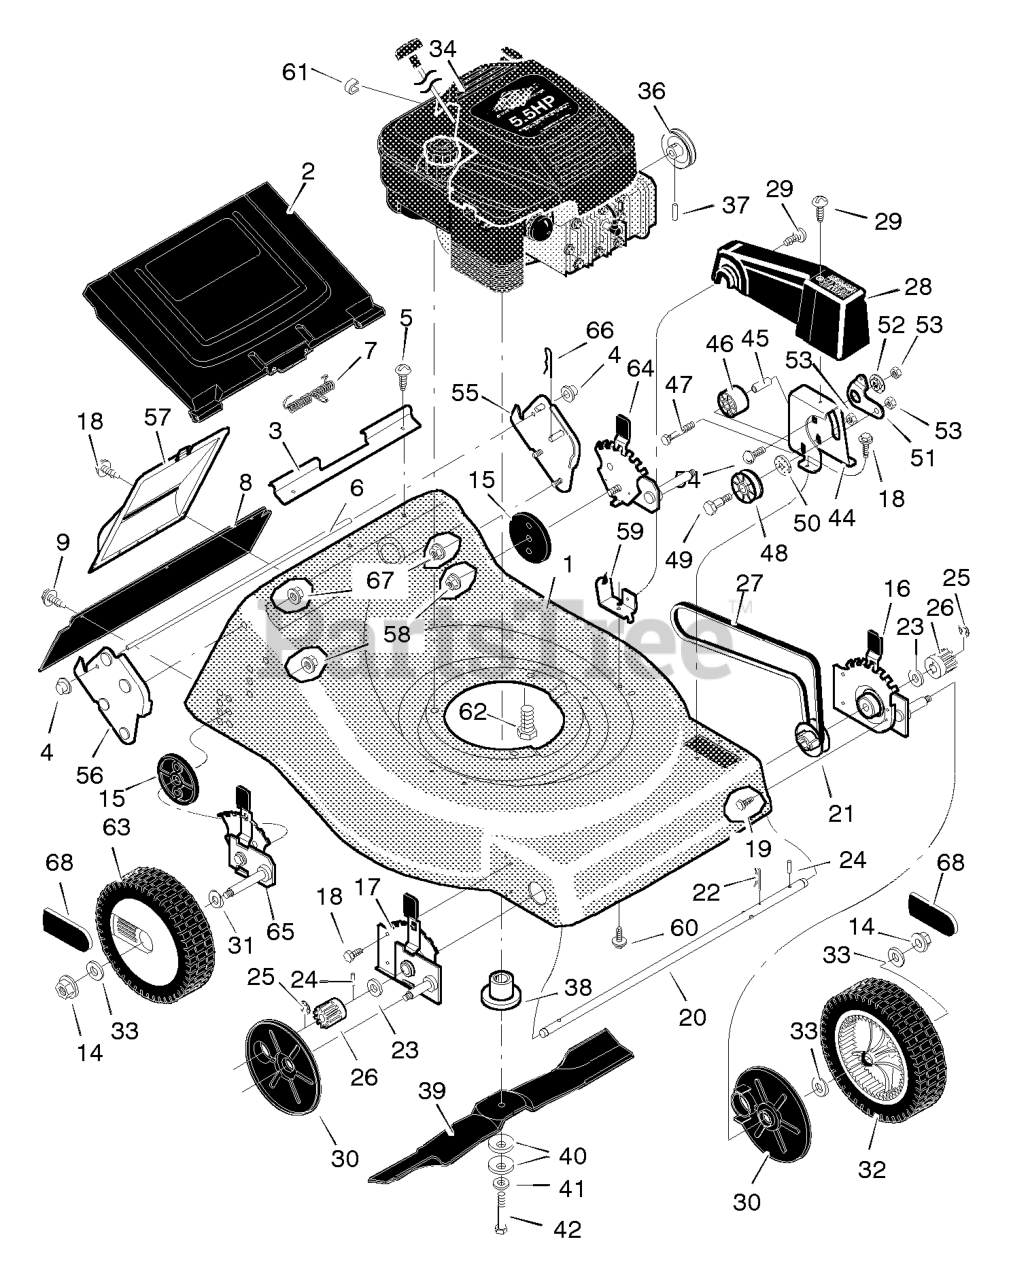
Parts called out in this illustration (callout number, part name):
1	Housing
2	Door, Rear
3	Spacer, Door
4	Push On Cap
6	Rod, Door Pivot
7	Spring, Torsion
8	Guard, Rear
14	Locknut, Flange
16	Height Adjuster, Left Front
17	Height Adjuster, Right Front
22	Hair Pin
24	Pin, Drive
25	Ring, Retainer
26	Gear, Pinion
27	Belt, Briggs Engine
28	Cover, Belt
30	Cover, Dust
32	Wheel, Drive
33	Washer
34	Engine *
36	Pulley, Engine
37	Pin, Spring
38	Adapter, Blade
40	Washer, Belleville
44	Bracket, Idler
45	Bearing
46	Pulley, Idler
48	Pulley, Idler
49	Bolt, Shoulder
51	Arm, Idler
53	Locknut
54	Bolt, Carriage
55	Handle Bracket, Left
56	Handle Bracket, Right
57	Cover, Transmission
58	Nut, Flange
59	Cable Bracket
61	Stop, Rope
62	Bolt, Engine Mount
63	WHEEL & TIRE ASSEMBLY, White, 8"
64	Height Adjuster, Rear
66	Pin, Hair
67	Nut, Hex
68	Hub Cap
